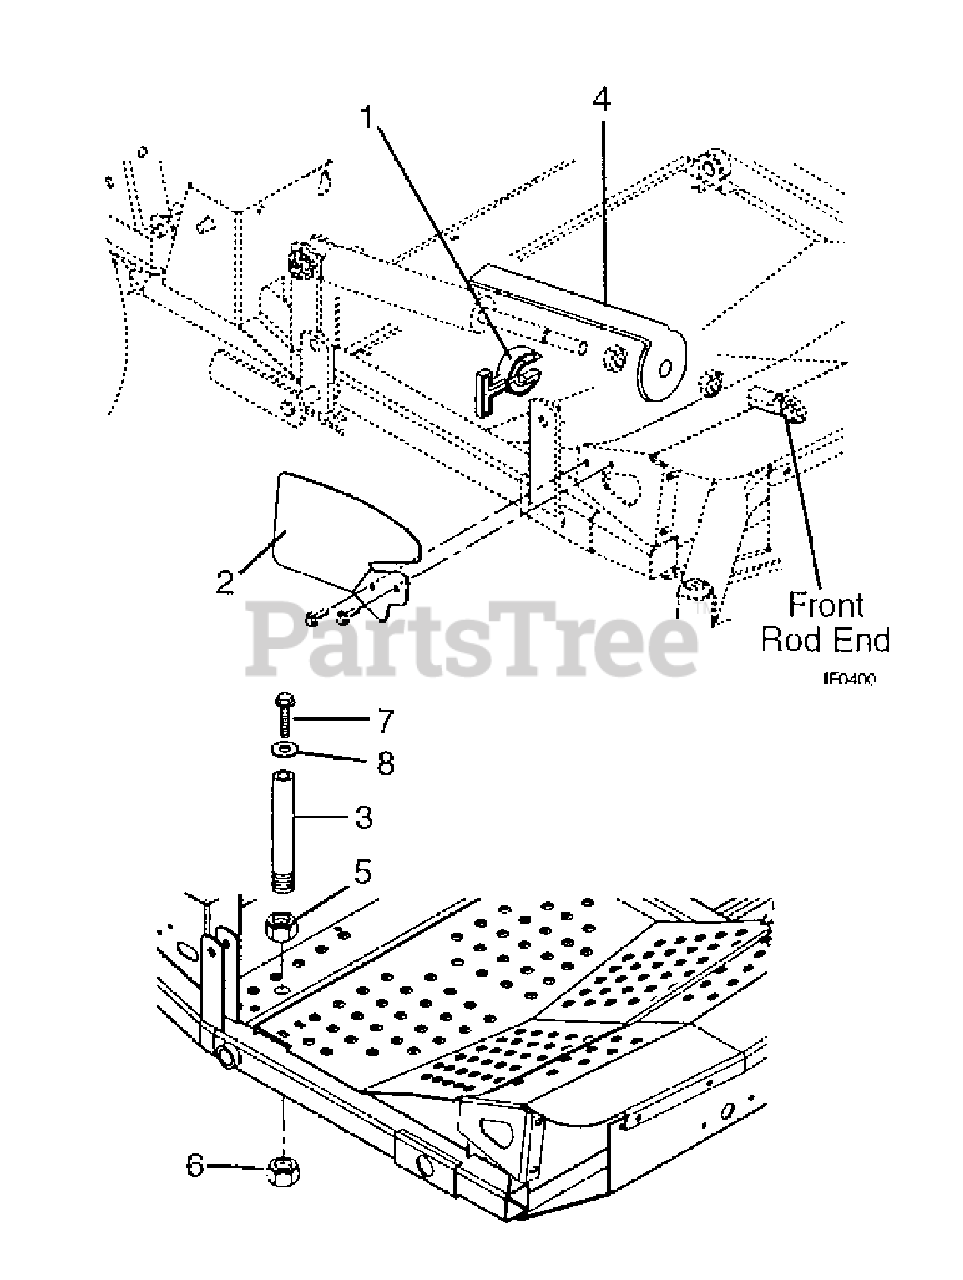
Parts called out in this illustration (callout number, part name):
1	Stop, Cylinder .34" Thick
1	Stop, Cylinder .68" Thick
2	Guard, Foot
3	Post
4	Strap, Height of Cut Indicator
5	Nut-Jam .75-16
6	Nut-Jam Center Lock .75-16
7	Bolt-Hex .50-20 x 1.00 Grade 5
8	Washer-Flat-Steel .531 x 1.06 x .095
